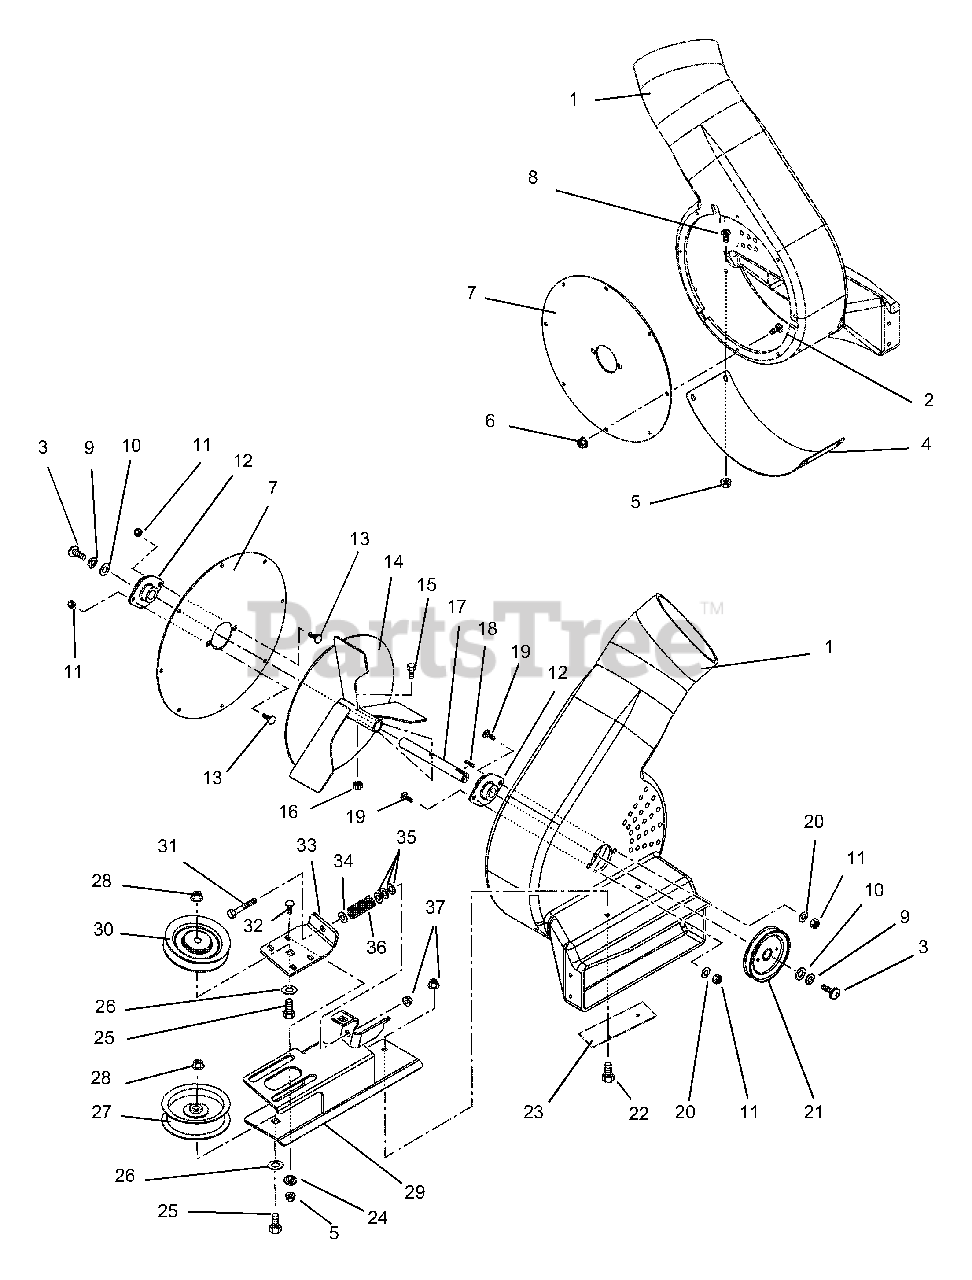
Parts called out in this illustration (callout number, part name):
1	BLOWER HSG W/DECAL
2	SCR-MCH .25-20X.63 TXTR YWZC
3	SCR-MCH .25-20X.75 TXTR YWZC
4	PLATE, SKID
5	@NUT-LK-TOP-FLG .25-20 YWZC
6	@NUT-SPNLK-FLG .25-20 YWZC
7	PLATE, BEARING MOUNT
8	SCR-MCH .25-20X.50 TXTR PL
9	@WSHR-LK .25X.062 REG YWZC
10	WSHR-FL-STL .344X1.125X.135
11	@NUT-LK-NYL .312-18 YWZC
12	BEARING, 2 BOLT FLANGE -.75 ID
13	@BLT-RHDSSQNK .31-18X.62 G5YZ
14	WELDMENT, IMPELLER, 3 BLADE
15	@BLT-HEX .25-20X1.50 GR5 YWZC
16	@NUT-LK-NYL .250-20 YWZC
17	SHAFT, IMPELLER
18	KEY-SQ .187 X .50 X .187
19	BLT-RDHDSQNK.31-18X.88 GR5YWZC
20	@WSHR-FL-STL.312X.734X.065 YWZ
21	SHEAVE, BLOWER - 4.25 DIA.
22	BOLT-HEX.31-18X.875 YWZC GR5
23	PLATE,BACK
24	BSHG-FLG .265X.437X.250X.750
25	@BLT-HEX .38-16X1.75 GR5 YWZC
26	@WSHR-FL-STL.406X.812X.065 YWZ
27	IDLER FLANGED 3.50
28	@NUT-LK-TOP-FLG .38-16 YWZC
29	WELDMENT, IDLER MOUNT
30	V-IDLER, 4.00X.38
31	@BLT-HEX .31-18X4.00 GR5 YWZC
32	@BLT-RDHDSQNK .25-20X.75 G5YZ
33	BRACKET, ADJUSTABLE IDLER
34	NUT-PUSH .312
35	WSHR-FL-STL .406X1.00X.188 YWZ
36	SG-COMP .092X.77X3.13 WLD 36
37	@NUT-LK-TOP-FLG .31-18 YWZC
38	BLOWER (SERVICE ASSEMBLY)
